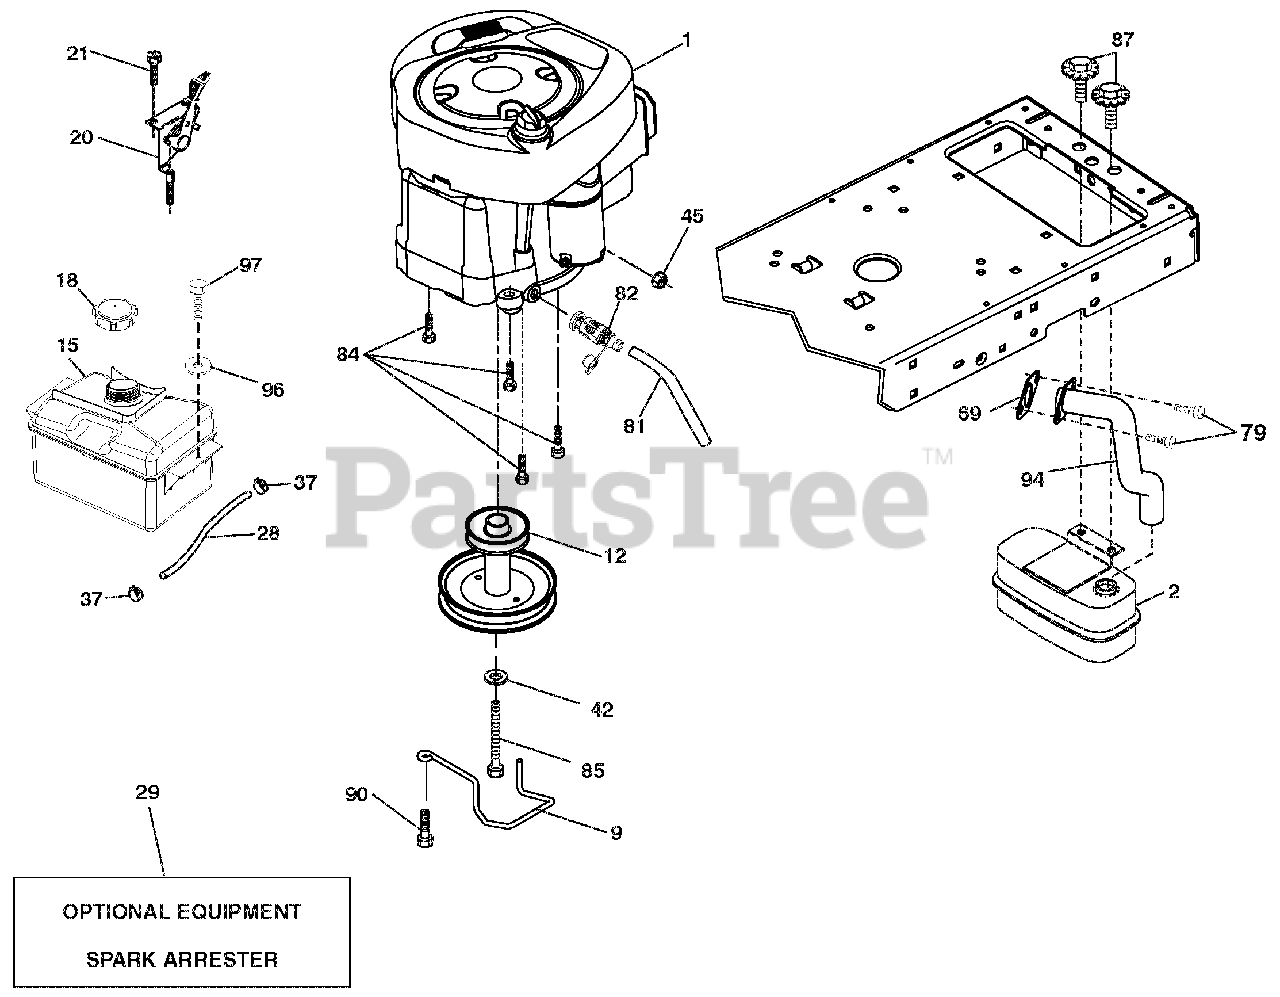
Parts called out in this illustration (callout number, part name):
1	ENGINE 331777-2372-G1
2	MUFFLER.SINGLE.CYL.KOHL.COURAG
9	KEEPER.BELT.ENGINE.4.25"NSTG
12	PULLEY ENGINE
15	TANK FUEL
18	CAP FUEL
20	CONTROL THROTTLE/CHOKE
28	LINE.FUEL.22"FRONT.EMIS.CA.LP
29	KIT.SPARK ARRESTOR(392390 B&S)
37	CLAMP.HOSE.BLK.
42	WASHER.LOCK.HVY HLCL.SPR.7/16
45	Nut, Keps Hex 1/4-20 unc
69	Gasket Eng 1 313 Id Tin Plated
79	SCREW.SOCKET HD.5/16-18 X .75
81	TUBE.DRAIN.OIL.EASY
82	VALVE OIL DRAIN
84	Screw 3/8-16 x <
85	BOLT.HEX.7/16-20X4XGR5-1.5THR.
87	BOLT.5/16-18UNCX3/4 W/SEMS.BLK
90	SCREW.3/8-16X1.SMGML.TAP/R.BLK
94	EXHAUST TUBE
96	WASHER.9/32 X 7/8 X 16GA.
97	SCREW.HEXWSH.THDROL.1/4-20X3/4
